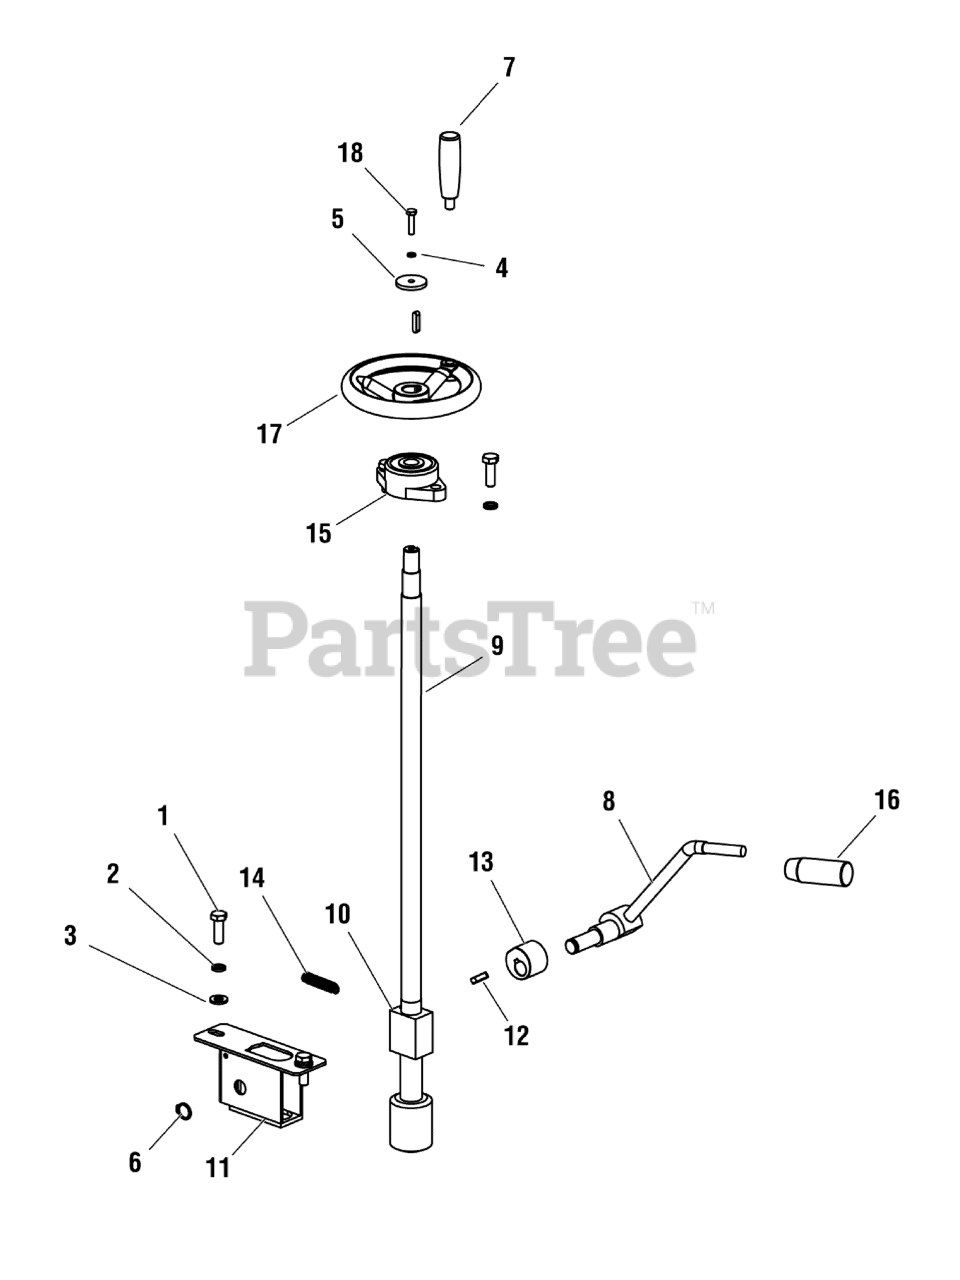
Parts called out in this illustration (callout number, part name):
1	BOLT, Hex, M10 x 30
2	WASHER, Spring, 10
3	WASHER, Flat, 10
4	WASHER, Spring
5	WASHER, Flat
6	CIRCLIP
7	HANDLE
8	HANDLE, Clutch
9	THREADED ROD
10	SLIDE BLOCK
11	CLUTCH SEAT
13	ECCENTRIC BLOCK
14	SPRING
15	BEARING
16	HANDLE
17	HANDLE, Wheel, Nylon
18	BOLT, Hex, M6 x 25
